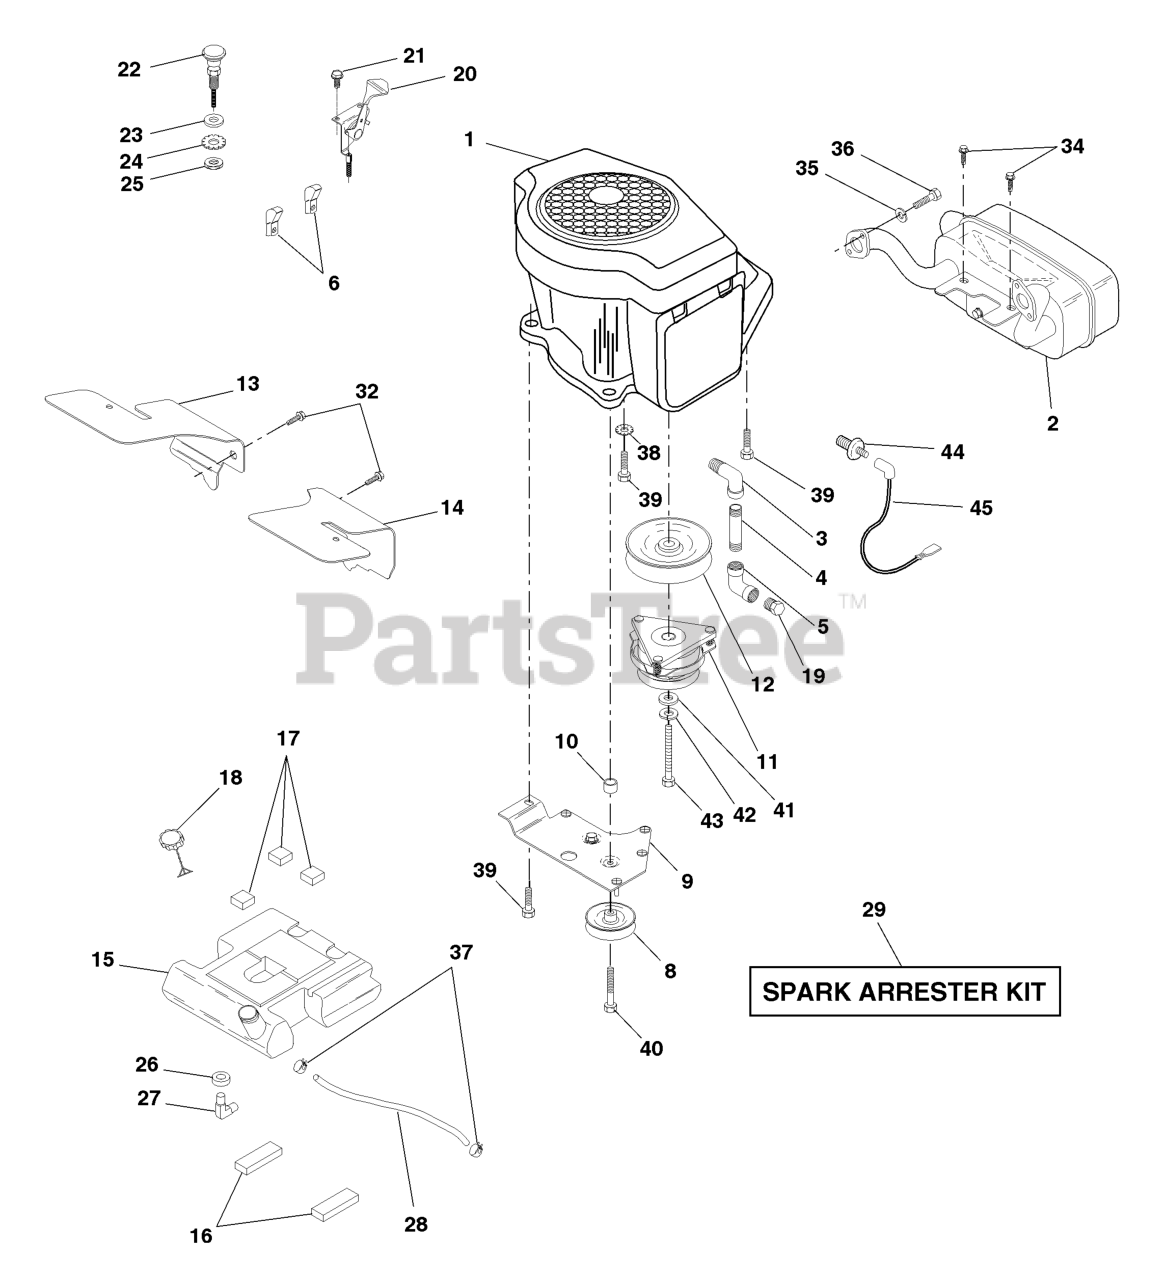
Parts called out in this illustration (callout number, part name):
3	STREET ELBOW LT NLA
4	Nipple Pipe 3/8NPT X 3 - 1/2
5	ELBOW
8	RP.IDLER GROOVED
9	STOP KEEPER
11	CLUTCH.ELECT.CVX.105 FT/LB.
12	PULLEY, ENGINE
13	AIR BAFFLE
14	AIR BAFFLE RH
15	FUEL TANK
16	PAD IDLER TI
17	PAD-SPACER LT
18	FUEL CAP
20	THROTTLE CONTROL
21	SCREW LT
22	CONTROL.CHOKE.51.00.BLK.W/BEND
23	WASHER
24	LOCKWASHER
25	NUT
26	BUSHING OUTLET T
27	STEM FUEL TANK
28	HOSE
29	SPARK ARRESTOR
32	Screw Thdrol 5/16 - 18 X 1/2
34	SCREW
35	WASHER.LOCK.HVY.HLCL.SPR.5/16
36	Screw Hex 5/16 - 16 UNC X 3/4
37	HOSE CLAMP
38	LOCKWASHER
39	SCREW LT
40	Screw Thdrol 3/8 - 16 X 3 - 1/4
42	LOCKWASHER
43	BOLT
44	SWITCH, OIL PRESSURE
